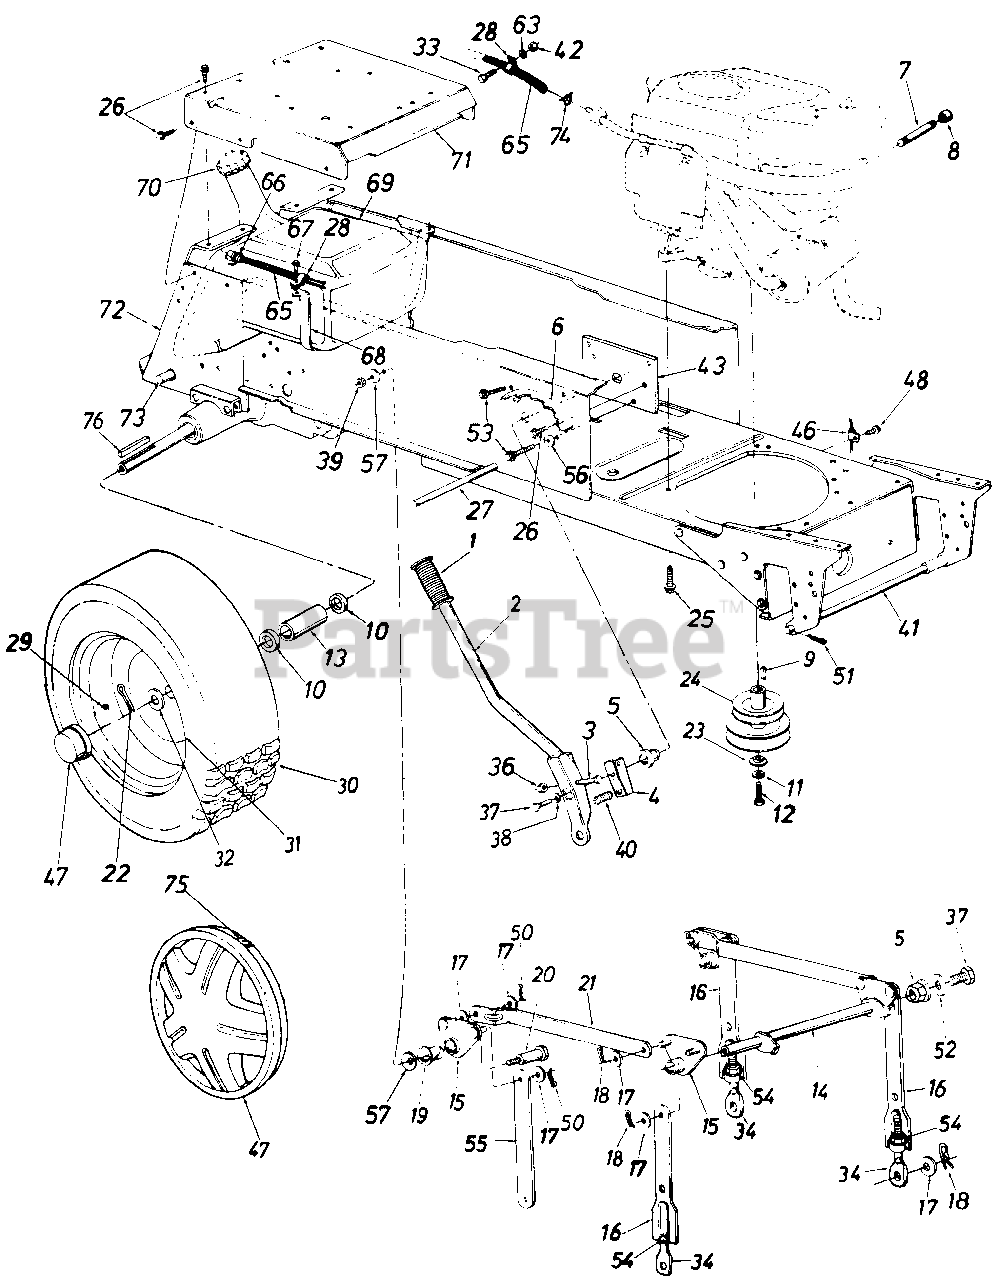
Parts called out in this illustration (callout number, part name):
1	Grip
2	Lift Handle Ass'y.
3	Hex Bolt 5/16-18 x 1.5" Lg.
4	Lift Shaft Drive
5	Plastic Hex Brg. 5/8" I.D.
8	Pipe Cap 3/8-18 Npt.
9	Sq. Key 1/4" x 1/4" x 1.50" Lg.
10	Fl-Wash. 1.03" I.D. x 1.62" O.D.
11	L-Wash. 7/16" I.D.
12	Hex Scr. 7/16-20 x 1.50" Lg.
13	Spacer 1.0" I.D. x 1.25" O.D.
14	Lift Shaft Ass'y.
15	Lift Pivot Brkt. Ass'y.
17	Fl-Wash. 1/2" I.D. x 1.00" O.D. x .090"
18	Hairpin Cotter
19	Nyliner 5/8" I.D. x .88" Lg.
20	Shld. Bolt 5/8" Dia. x .96" Lg. 3/8-16
23	Flat Wash..44" I.D. x 1.25" O.D. x .17"
24	Two-Step Engine Pulley
25	Hex Wash. Hd. Scr. 3/8-16 x 1.25" Lg.
26	Hex Thd. Rolling Scr. 5/16-18 x .75" Lg.
27	Running Board Rod
28	Clamp
29	Air Valve
33	Hex Bolt 1/4-20 x .62" Lg.
34	Eye Bolt Adj. Link 1/2-13 Thd.
36	Hex Cent. L-Nut 5/16-18 Thd.
37	Hex Bolt 5/16-24 x .62" Lg.
38	L-Wash. 5/16" I.D.
39	Hex Top L-Nut 3/8-16 Thd.
40	Compression Spring
41	Deck Connecting Rod
42	Hex Nut 1/4-20 Thd.
47	Hub Cap
48	Hex Wash. Hd. TT-Tap Scr. 1/4-20 x .5" Lg.
50	Cotter Pin .09 Dia. x 1.0" Lg.
51	Int. Cotter Pin
52	Flat Wash..34" I.D. x 1.12" O.D. x .125"
53	Hex Wash. Hd. AB-Tap Scr. 5/16-24 x .5" Lg.
54	Hex Nut 1/2-13 Thd.
56	Fl-Wash. .344" I.D.
57	Bell-Wash..4" I.D. x 1.13" O.D.
63	L-Wash. 1/4" I.D.
65	Fuel Line 46" Lg.
66	Hose Clamp
67	Hex AB-Tap Scr. 1/4 x .62" Lg.
68	Fuel Tank Strap
69	Gas Tank
70	Gas Gauge
74	Hose Clamp
75	Spring Clip
76	Sq. Key 1/4" x 3" Lg.
